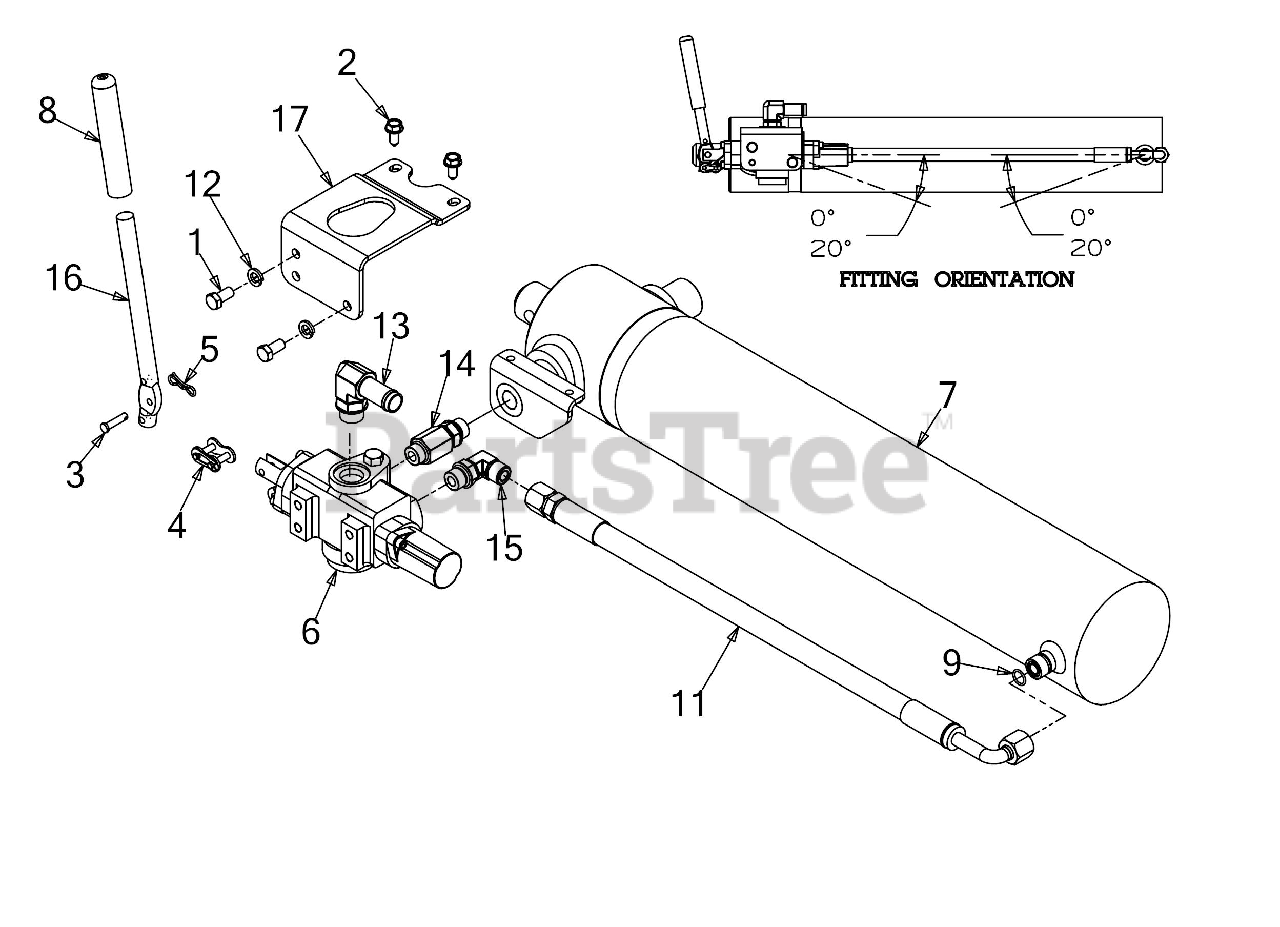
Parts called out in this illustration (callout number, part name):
1	HEX SCREW 3/8-16 x .75
2	SCREW 5/16-18 x .750
3	CLEVIS PIN .25 x 1.00
4	VALVE HANDLE LINK
5	BOW TIE COTTER PIN 1/4-5/16
6	LOGSPLITTER VALVE
7	HYDRAULIC CYLINDER
9	O-RING
11	HYDRAULIC HOSE
12	LOCK WASHER 3/8
13	HYDRAULIC FITTING 7/8 ORB X .75 BEAD
14	HYDRAULIC FITTING 3/4 ORB
15	HYDRAULIC FITTING 3/4ORB X 13/16ORFS
16	CONTROL VALVE HANDLE
17	VALVE BRACKET
